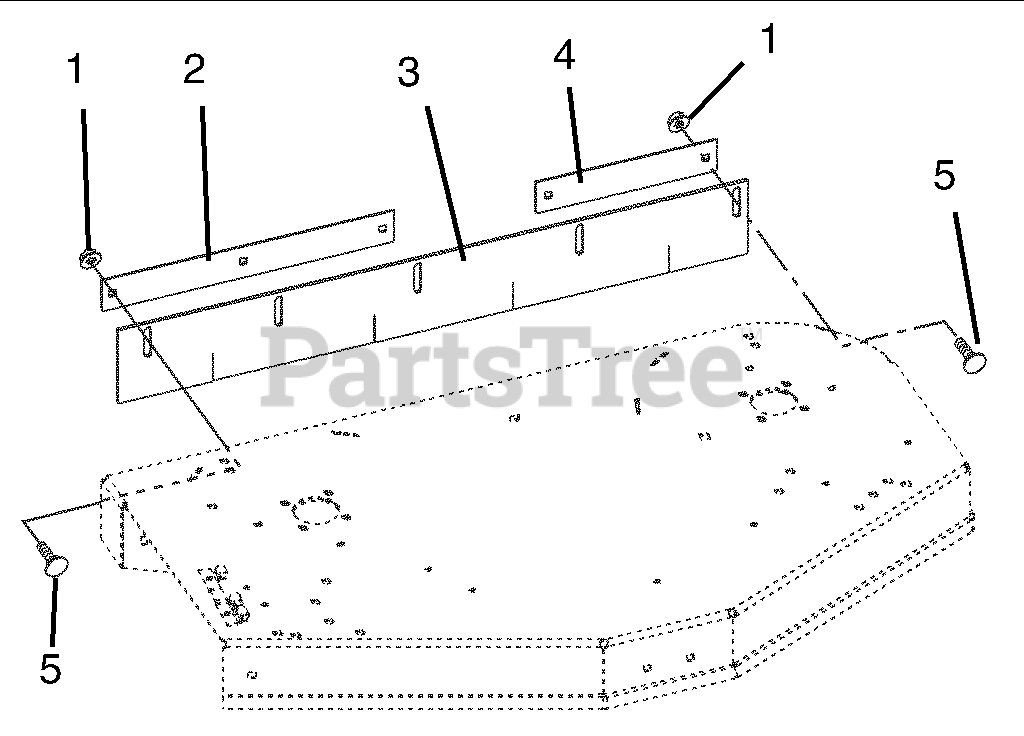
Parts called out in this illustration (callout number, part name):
1	3/8" Nylon Locknut
2	Right Hand Retainer Striper Bar
3	Rubber Striper
4	Left Hand Retainer Striper Bar
5	3/8" x 1" Round Head Square Neck Bolt
